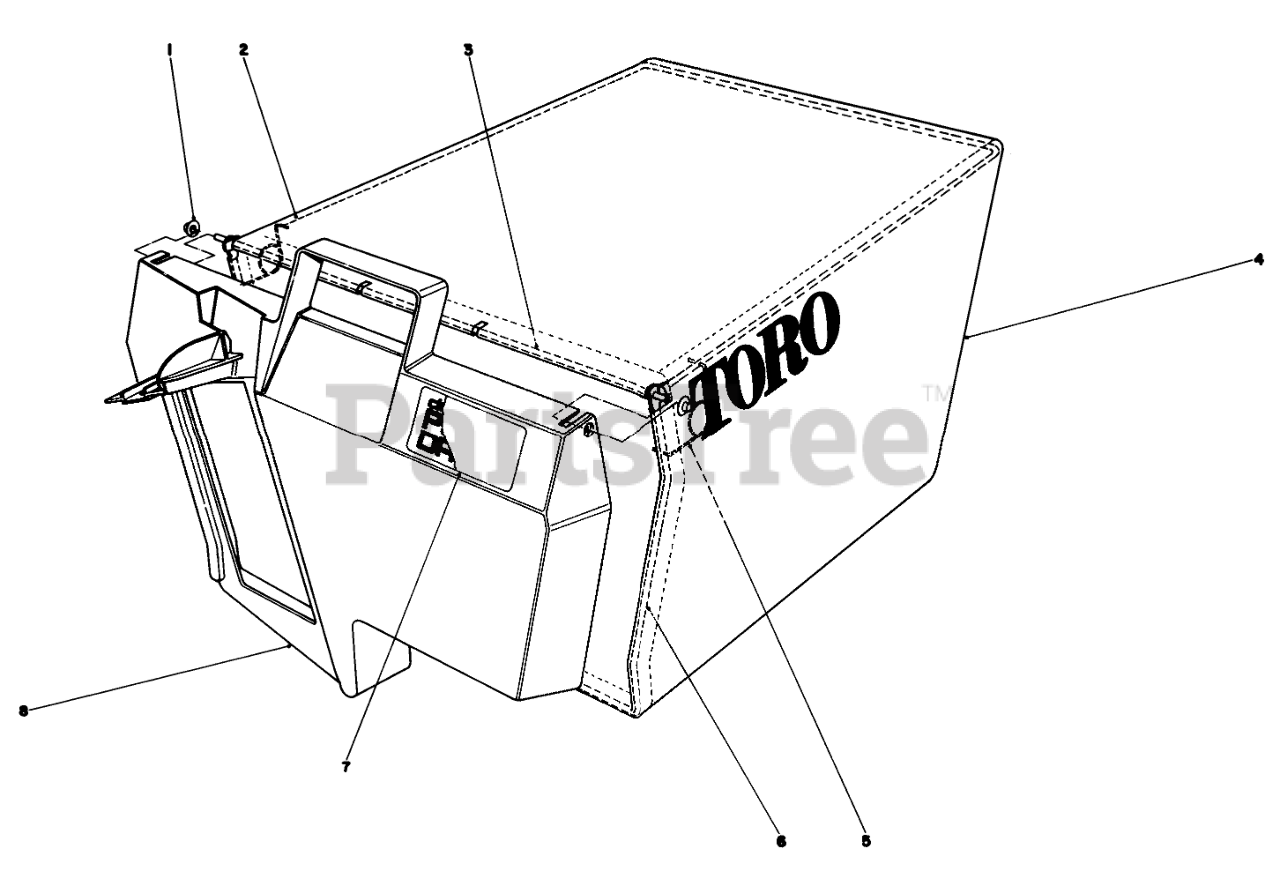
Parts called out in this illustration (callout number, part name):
1	Nut-Push
2	Bag Frame Upper
3	HingeBag Door
4	Bag
5	SPRING
6	Frame Bag
7	BAG DOOR DECAL
8	Door Grass Bag
